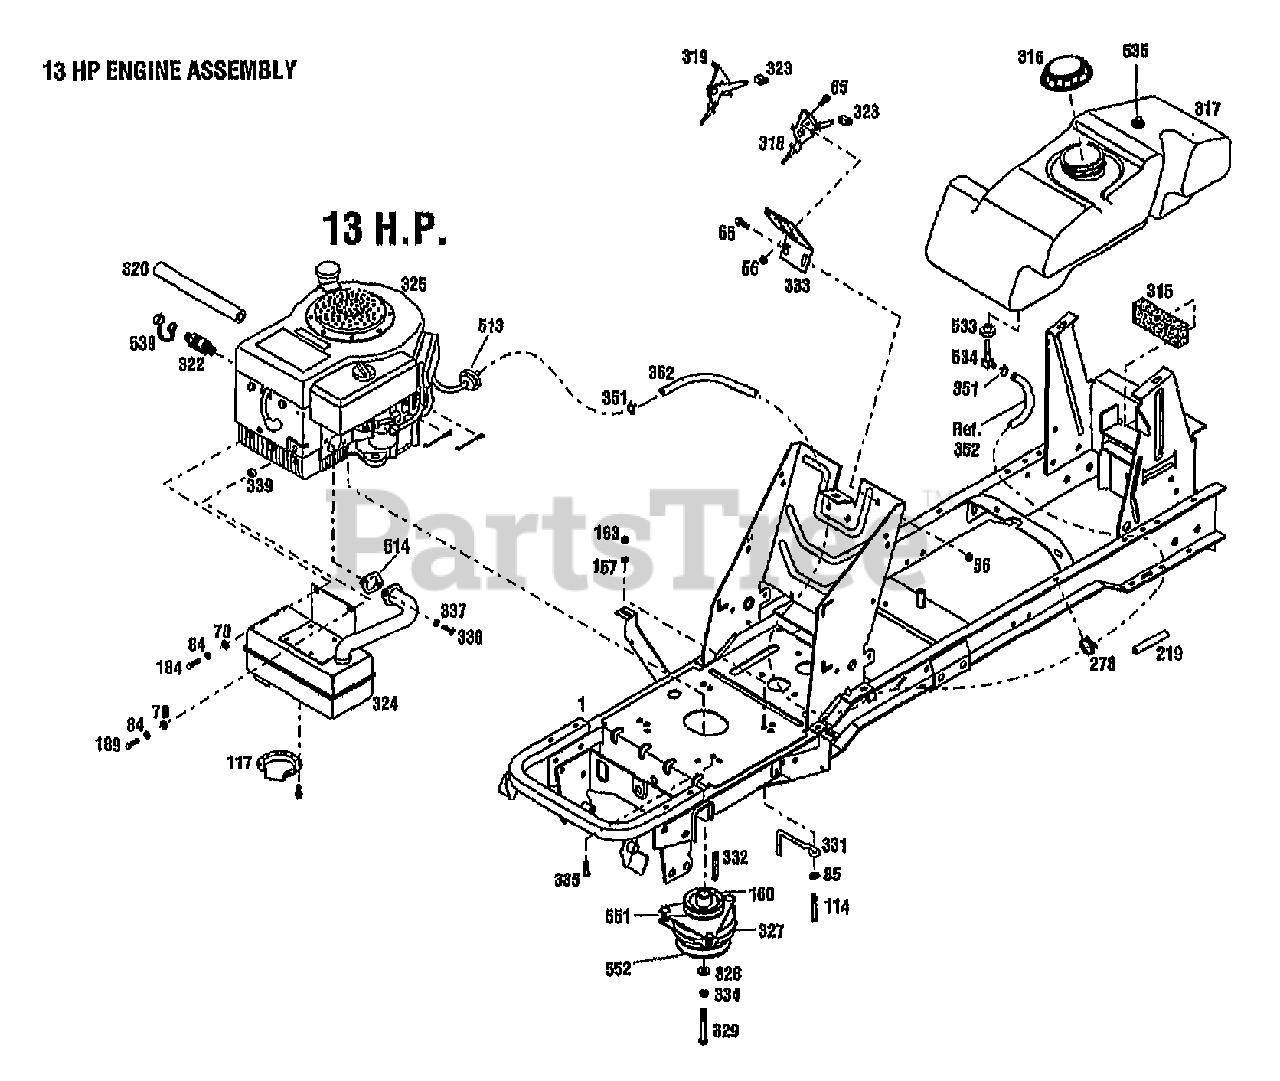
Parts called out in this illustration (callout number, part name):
1	ASSM-FRAME LTX
56	NUT-HF/LK 1/4-20 ZP
65	SCR-HH 1/4-20X.625
70	WASHER-FLAT 1/4 SAE
84	WASHER-LK .25 ZP
85	WASHER-FLAT 3/8 SAE
114	SCR-THRD FRM 3/8-16X1.50
117	DEFLECTOR-MUFFLER
160	PULLEY-ENGINE
163	NUT-HEX 3/8-16 ZP
167	WASHER-LK .375 @ DEPL
184	SCR-HH 1/4-20 X .875
189	SCR-HH 1/4-20X1.25
278	TIE-CABLE NYLON BLACK
315	PAD-FUEL TANK
316	CAP-FUEL
317	TANK-FUEL
318	CONTROL-THROTTLE
319	CONTROL-CHOKE
320	HOSE-OIL DRAIN
322	ASSM-OIL VALVE
324	MUFFLER
325	ENGINE, 13HP B&S DIAMOND PLUS (13084) #28M707-0615 A1 (CARB)
327	CLUTCH-ELECTRIC
328	WASHER-SPEC 1.42X.468X.25 ZP
329	SCR-HH 7/16-20X3.00
331	CLUTCH-RETAINER
332	KEY-.25 SQ X 2.5
333	BRKT-MOUNTING CONTROL
334	WASHER-LK .438 ZP
335	SCR-HH 3/8-16X1.0 THDFM
337	WASHER-LOCK
338	SCR-HXSKT 5/16-18X.75 BO
339	SPACER-.625X.344X.34
351	CLAMP-HOSE
352	LINE-FUEL
513	FILTER-FUEL
514	MUFFLER GASKET
533	BUSHING-RUBBER
534	ELBOW-90 DEG (FUEL LINE)
535	VENT-FUEL TANK
539	CAP-OIL DRAIN
551	BEARING-UPPER CLUTCH
552	BEARING-CLUTCH LOWER
